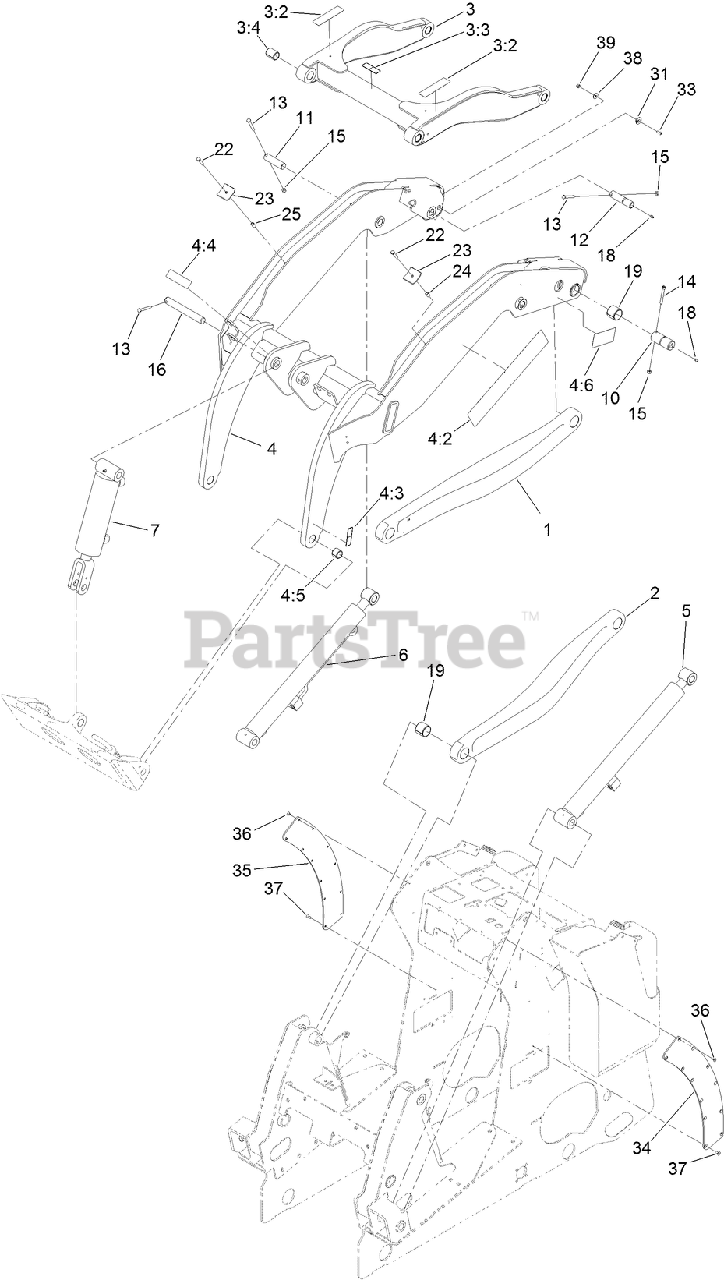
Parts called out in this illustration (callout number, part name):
1	LINK-LOWER, LH
2	LINK-LOWER, RH
3	LINK-UPPER
3:2	DECAL-WARNING, CRUSHING
3:3	DECAL-WARNING, PINCH POINT
3:4	BUSHING-SPRING
4	ARM-LOADER
4:2	DECAL-TX1000,
4:3	DECAL-WARNING, PINCH POINT
4:4	DECAL-CAUTION
4:5	BUSHING-TENSION
4:6	DECAL-WARNING, PINCH POINT
5	CYLINDER-LIFT, LH
6	CYLINDER-LIFT, RH
7	CYLINDER-HYD, DUMP
10	PIN-ARM
11	PIN-PIVOT
12	PIN-LINK
13	SCREW-HH
14	SCREW-HSH
15	NUT-LOCK, NI
16	PIN-LOCKING
18	FITTING-GREASE
19	BUSHING-SPRING
22	SCREW-HH
23	PLATE-HOLDDOWN, HOSE
24	SPACER-HOSE
25	SPACER-HOSE
33	SCREW-HSBH
34	WEAR PAD-FRAME, LEFT
35	WEAR PAD-FRAME, RIGHT
36	SCREW
37	SCREW-HSFH
38	WASHER-PLAIN
39	NUT-LOCK, NI
